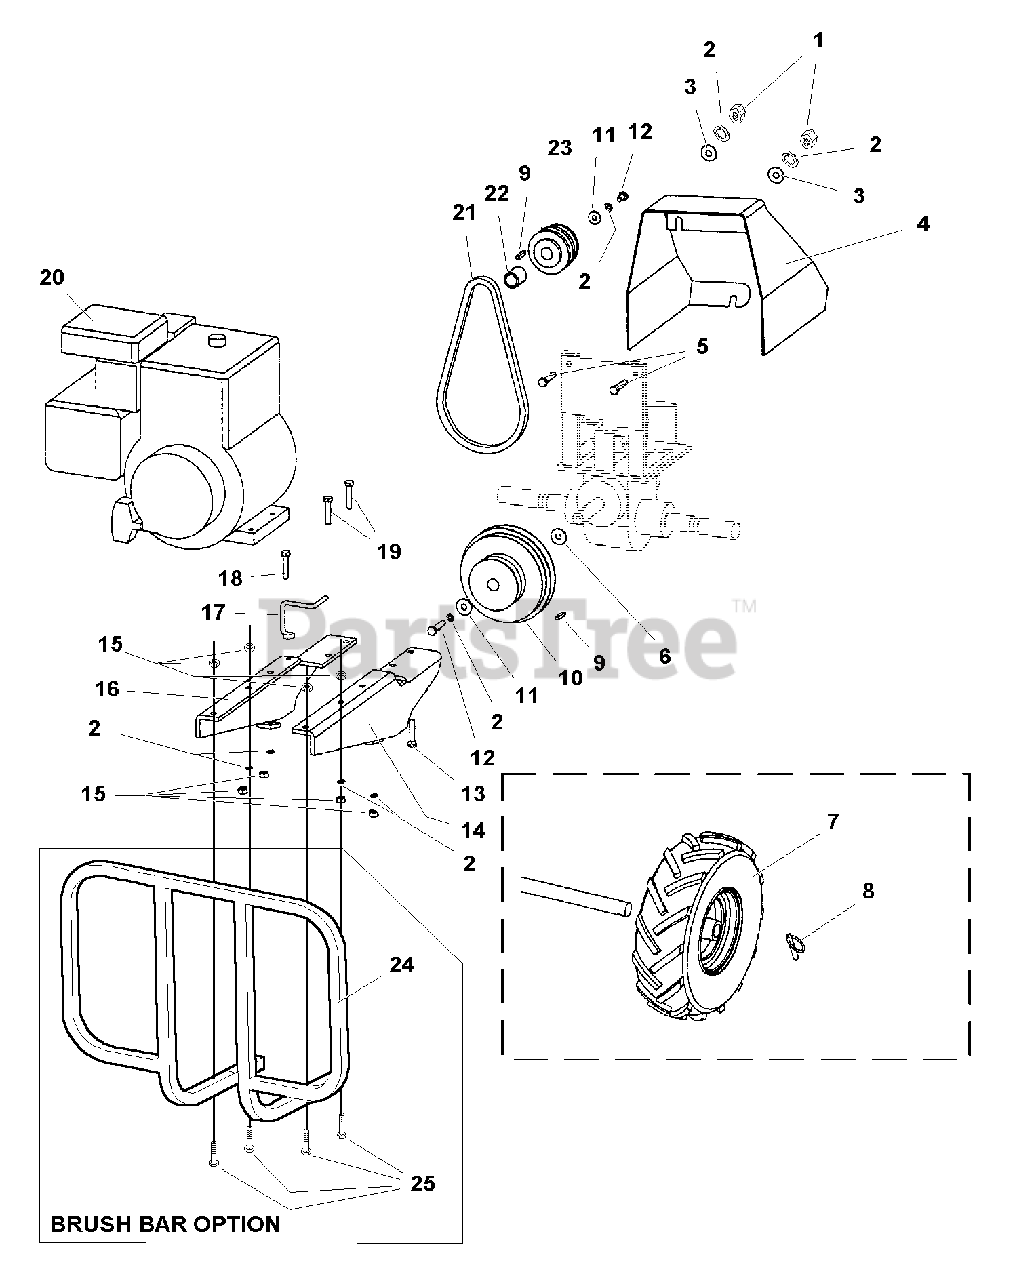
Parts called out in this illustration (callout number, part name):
1	NUT, Hex, 5/16"-18NC, 2B
2	LOCKWASHER, Spring 5/16"
3	WASHER, 5/16"
4	COVER, Belt
5	CAPSCREW, Hex Head 5/16-18 x 2 G5
6	WASHER, 5/8"
7	WHEEL & TIRE ASSEMBLY, Right
7	WHEEL & TIRE ASSEMBLY, Left
8	PIN, Lock
9	KEY, Parrallel
10	PULLEY, Transmission
12	CAPSCREW, 5/16"-24 x 3/4" G5
13	CAPSCREW, Hex Socket Head, 5/16"-18 x 11/4" G8
14	BRACKET, Engine Mount LH
15	NUT, Hex Flange Head, 5/16"-18 TWO, WAY Lock
16	BRACKET, Engine Mount RH
17	GUIDE, Belt Forward
18	CAPSCREW, 5/16"-24 x 1/2"
19	CAPSCREW, 5/16"-18 x 1 3/4" G5
22	SPACER, Engine Pulley
23	PULLEY, Engine, Forward
